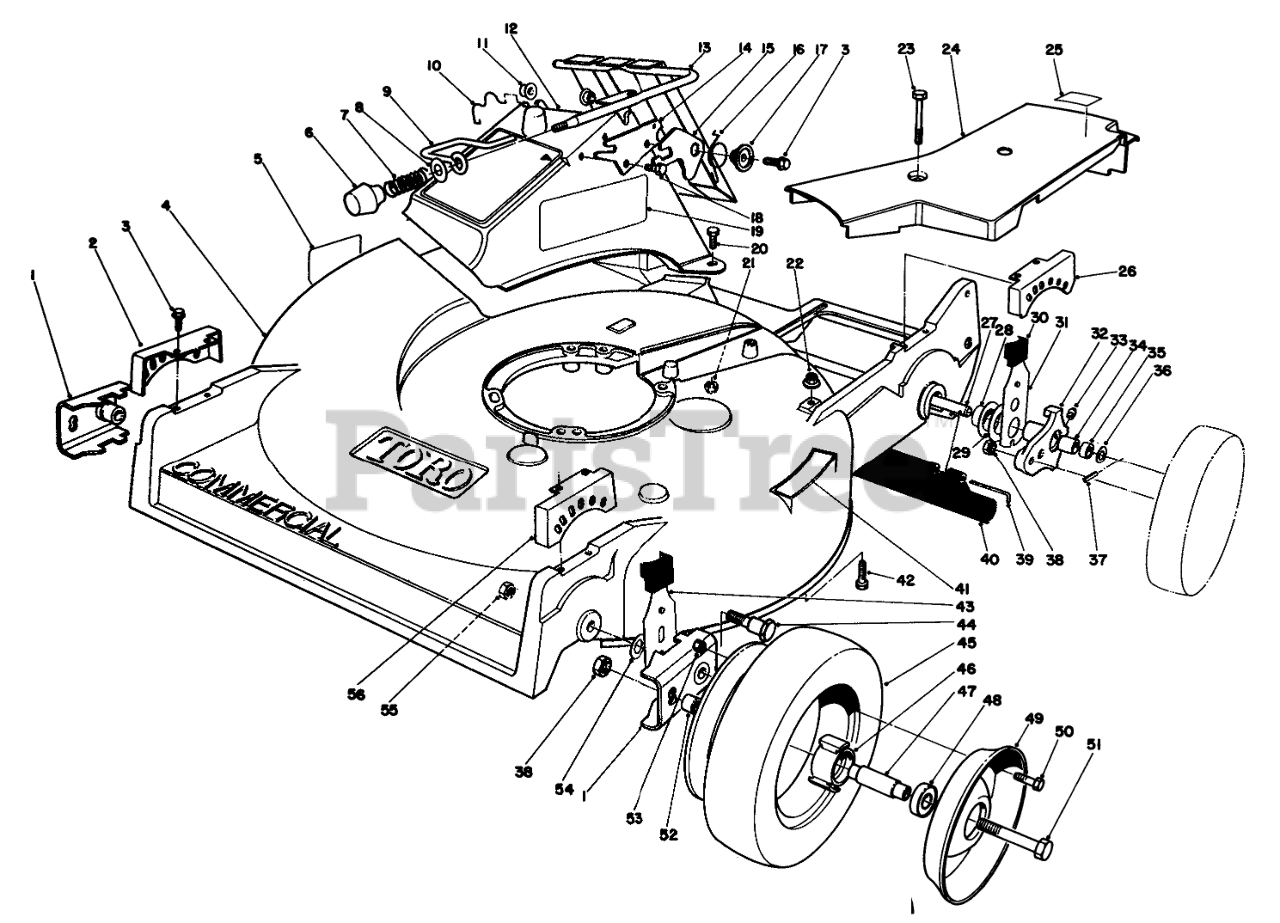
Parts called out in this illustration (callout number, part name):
1	PIVOT ARM
2	QUADRANT-FRONT, RH
3	Screw
4	Housing (Incl Ref. #5 & 41)
5	DECAL-DANGER
7	COMPRESSION SPRING
8	WASHER-FLAT
9	DOOR LATCH
10	DOOR RETAINER
11	BUSHING-NYLON
12	Chute & Door Assembly (Incl Ref. #3 & 6-21)
13	DOOR & HANDLE WA
14	DOOR LATCH PLATE
15	SAFETY LATCH
16	TORSION SPRING
17	DOOR SPACER
18	SCREW-HWH
19	DECAL SAF INST
20	SCREW-HH
21	NUT-LOCK, NI
22	NUT-HF
23	SCREW-HHFTF
24	Belt-Cover
25	LABEL-GREASE, HP
26	QUADRANT-REAR, LH
27	SHAFT-AXLE, REAR
28	CAP-END
29	WASHER
30	KNOB-ARM
31	Spring Arm
32	Pivot Arm (Incl. Ref. #33-35)
33	FITTING-GREASE
34	BUSHING
35	BUSHING
36	WASHER-PLAIN
37	PIN-SPIROL
38	NUT-LOCK, CONE
39	ROD-SHIELD
40	SHIELD-TRAILING
41	STEP PAD DECAL
42	SCREW-HH
43	SPRING ARM ASM-FRONT
44	PIVOT SCREW
46	HUB-BEARING
47	SPACER-BEARING
48	BEARING-WHEEL
49	Wheel-Half
50	SCREW-HHF
51	SCREW-HH
52	SPACER-WHEEL
53	NUT-LOCK, NI
54	WASHER-PIVOT
55	NUT-LOCK, NI
56	QUADRANT-FRONT, LH
